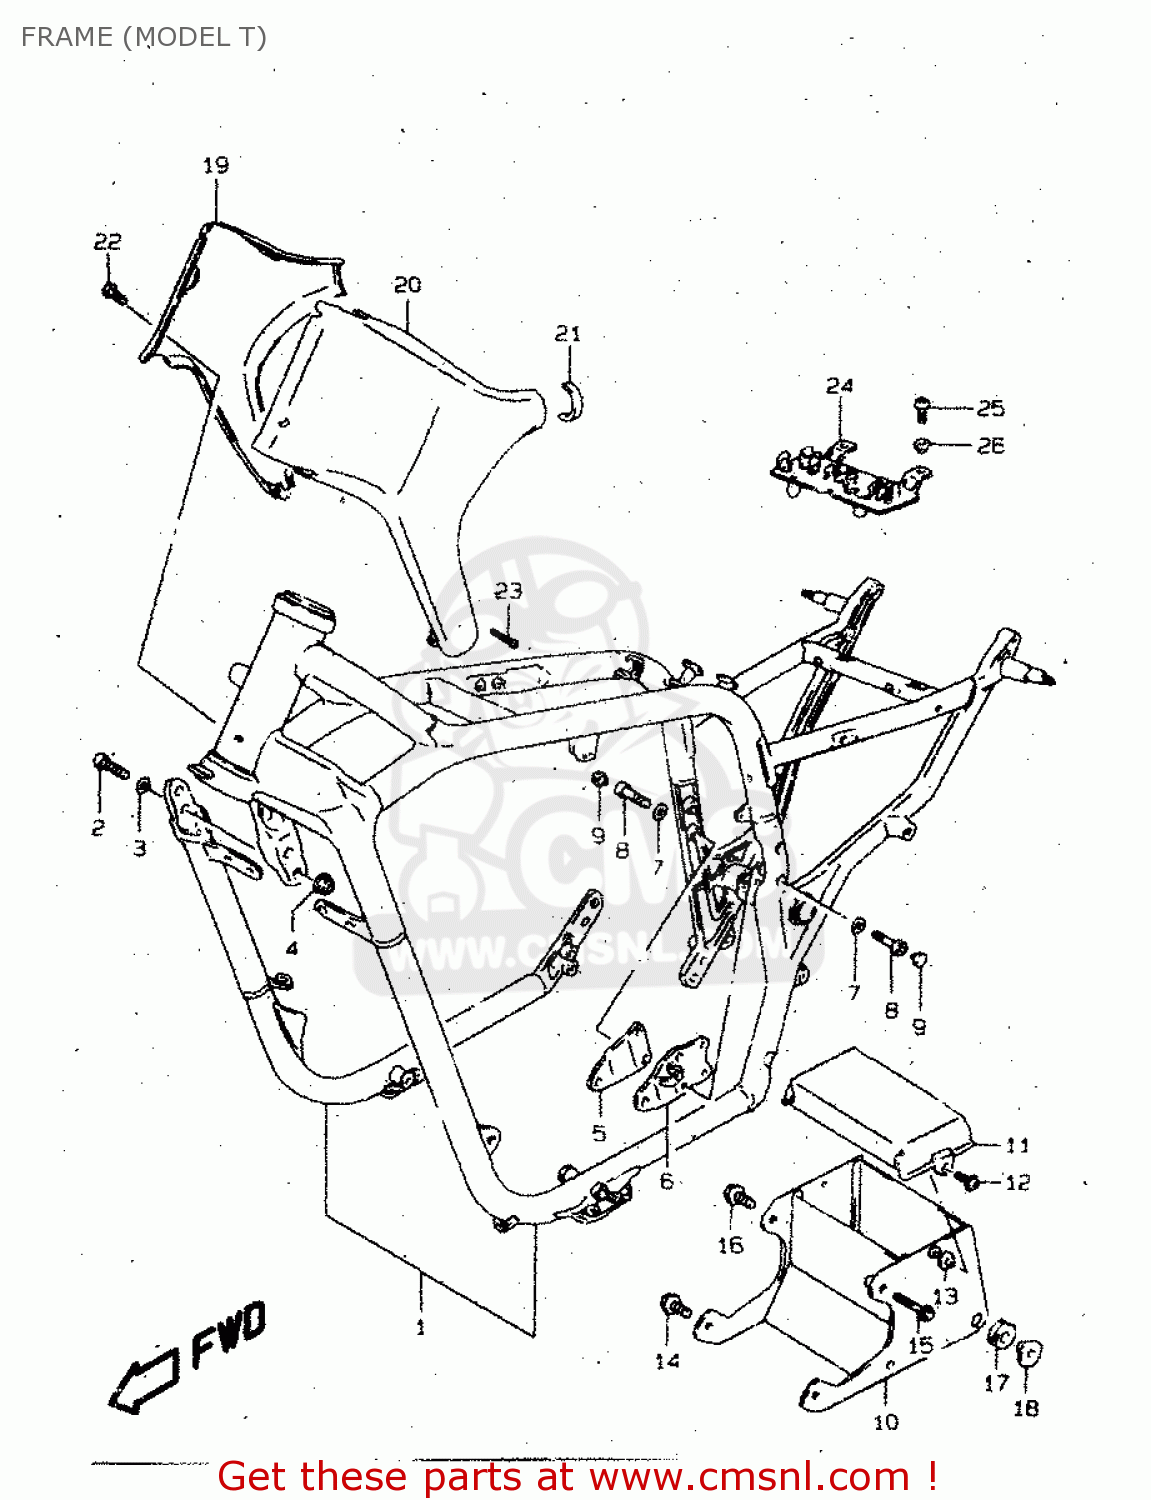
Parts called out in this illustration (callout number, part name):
1	FRAME SET
2	BOLT(10X33)
3	WASHER
4	NUT 10MM
5	PLATE,ENG MTG NO.4,R
6	PLATE,ENGINE MOUNT NO.4,L
7	WASHER
8	BOLT(8X32)
9	CAP(OD:14.5)
10	HOLDER COMP,BATTERY
11	COVER,BATTERY
12	SCREW(5X12)
13	WASHER
14	BOLT
15	BOLT
16	BOLT(8X40)
17	CUSHION
18	BUSH
19	COVER,FRAME HEAD,R
20	COVER,FRM.HD.,
21	PROTECTOR,FRAME HEAD COVER
22	SCREW 6X10
23	SCREW
24	HOLDER,COUPLER
25	SCREW
26	WASHER
